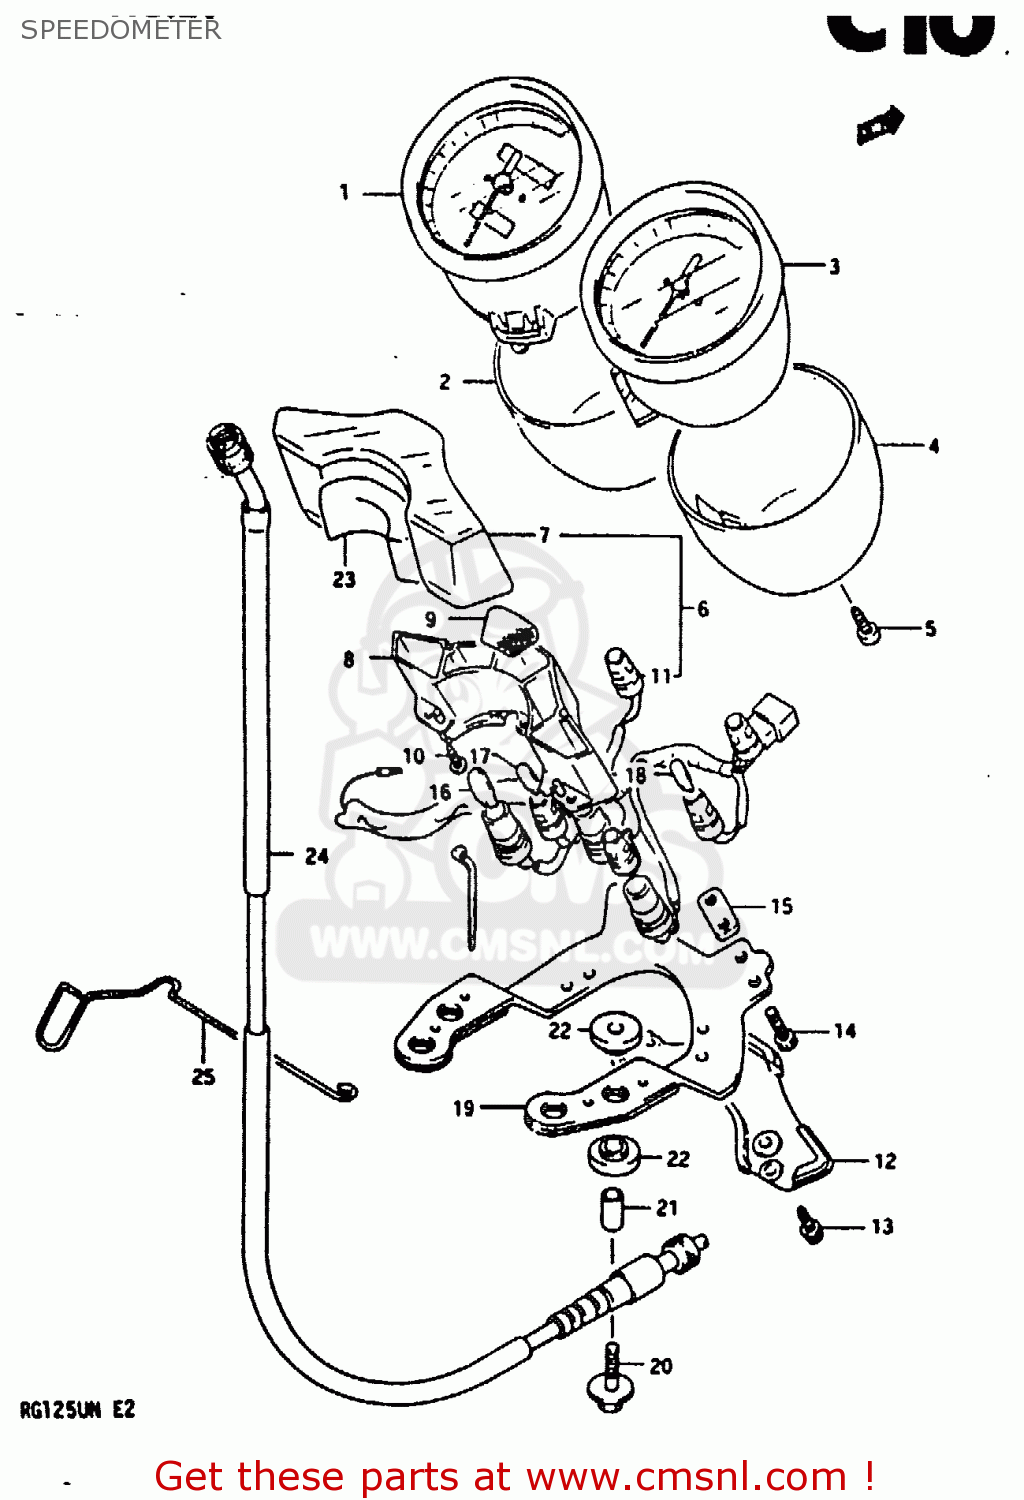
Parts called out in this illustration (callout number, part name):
1	SPEEDOMETER (KILO)
2	LWR CASE,SPEEDOMETER
3	TACHOMETER
4	LWR CASE,TACHOMETER
5	SCREW,METER
6	BOX, PILOT
7	UPR CASE
8	INNER CASE
9	LENS SET
10	SCREW
11	SOCKET
12	LOWER CASE
13	SCREW
14	BOLT
15	PLATE
16	BULB(12V3.4W,T10,BF175-01450A)
17	BULB(12V3W,WB371,T7)
18	BULB(12V1.7W,WB372,T7)
19	BRACKET, METER
20	BOLT(6X25)
21	SPACER
22	CUSHION
23	CUSHION, PILOT LAMP
24	CABLE ASSY, SPEEDOMETER
25	GUIDE,SPEEDOMETER CABLE
